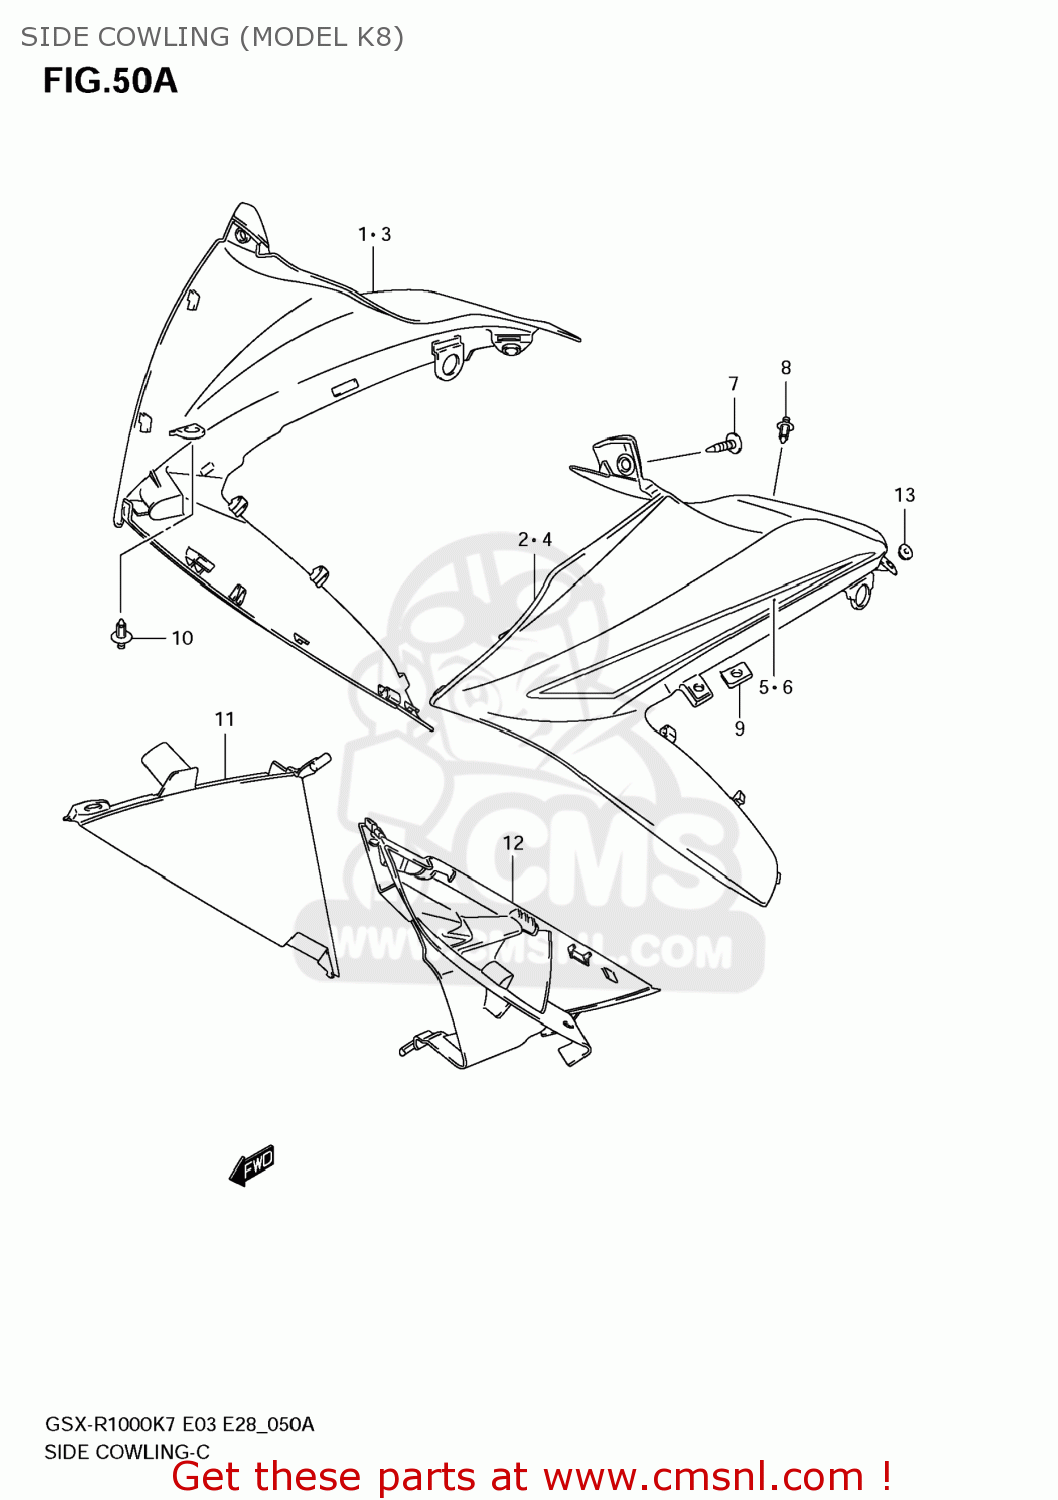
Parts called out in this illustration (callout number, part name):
1	COWLING,SIDE,R
2	COWLING,SIDE,L
3	COWLING,SIDE,R(SILVER)
4	COWLING,SIDE,L(SILVER)
5	TAPE,COWL SIDE,R
6	TAPE,COWL SIDE,L
7	SCREW(5X12)
8	CLIP
9	NUT
10	CLIP(BLACK)
11	COWLING,UNDER INNER,R
12	COWLING,UNDER INNER,L
13	CUSHION
